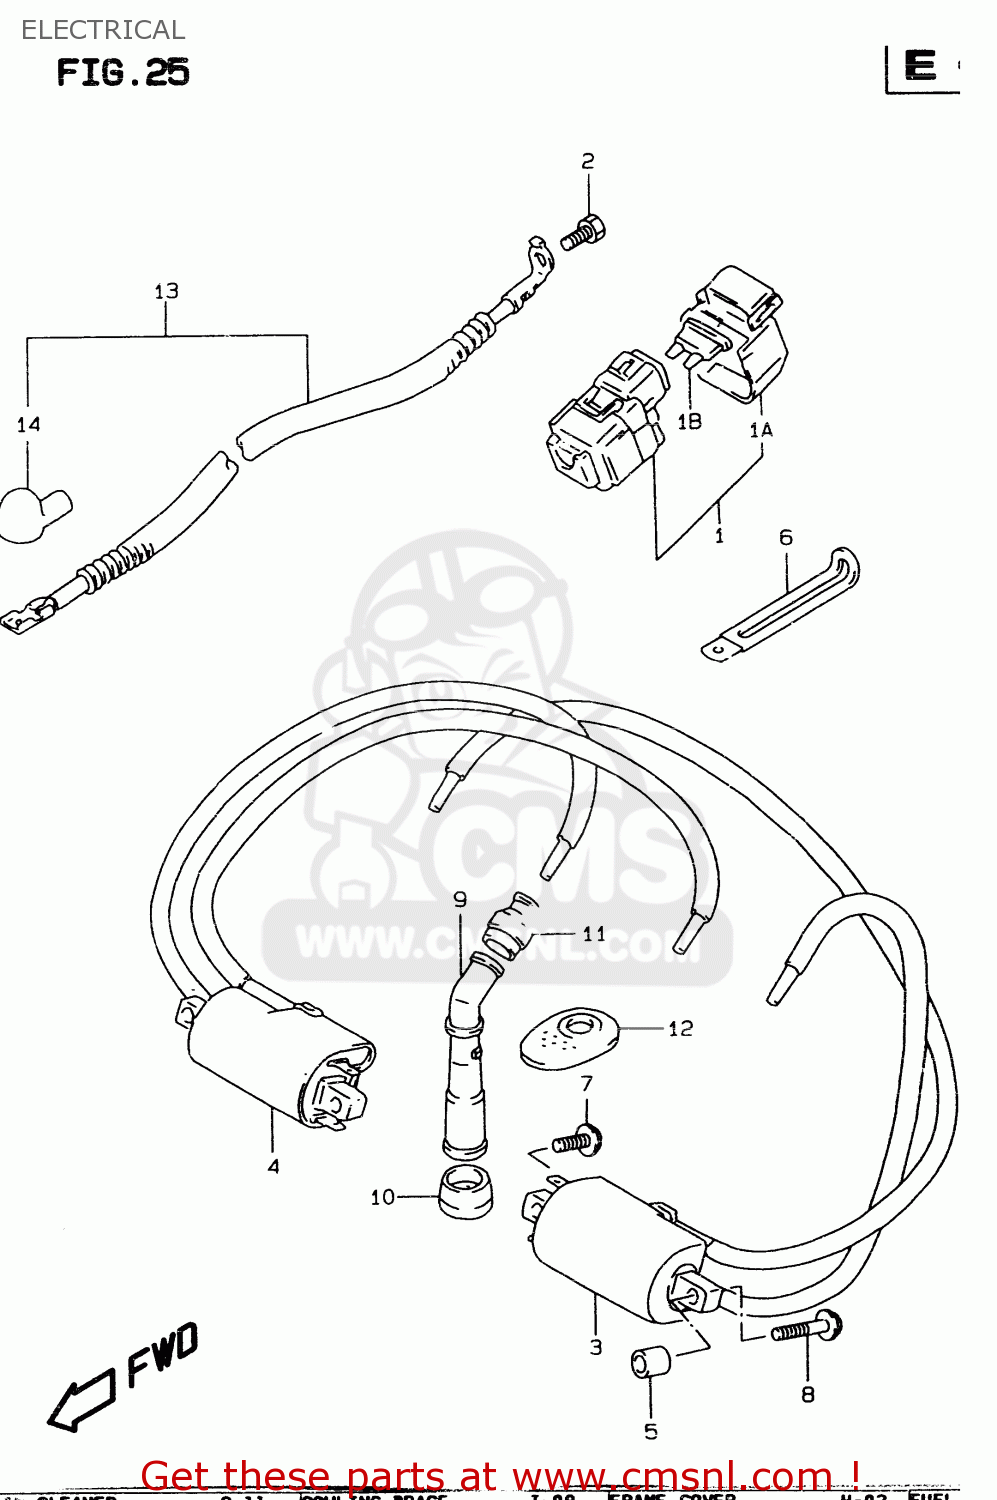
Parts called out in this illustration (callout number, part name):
1	RELAY ASSY,STARTING MOTOR
1A	COVER,STARTER RELAY
1B	FUSE(30A)
2	SCREW(6X8)
3	COIL ASSY,IGNITION
4	COIL ASSY,IGNITION
5	SPACER(6X12X10)
6	CLAMP(L:65)
7	BOLT
8	BOLT
9	CAP,SPARK PLUG
10	SEAL,SPARK PLUG CAP
11	SEAL,HIGH TENSION CORD
12	COVER,SPARK PLUG CAP
13	WIRE,STARTER MOTOR LEAD
14	CAP,STARTER MOTOR TERMINAL
